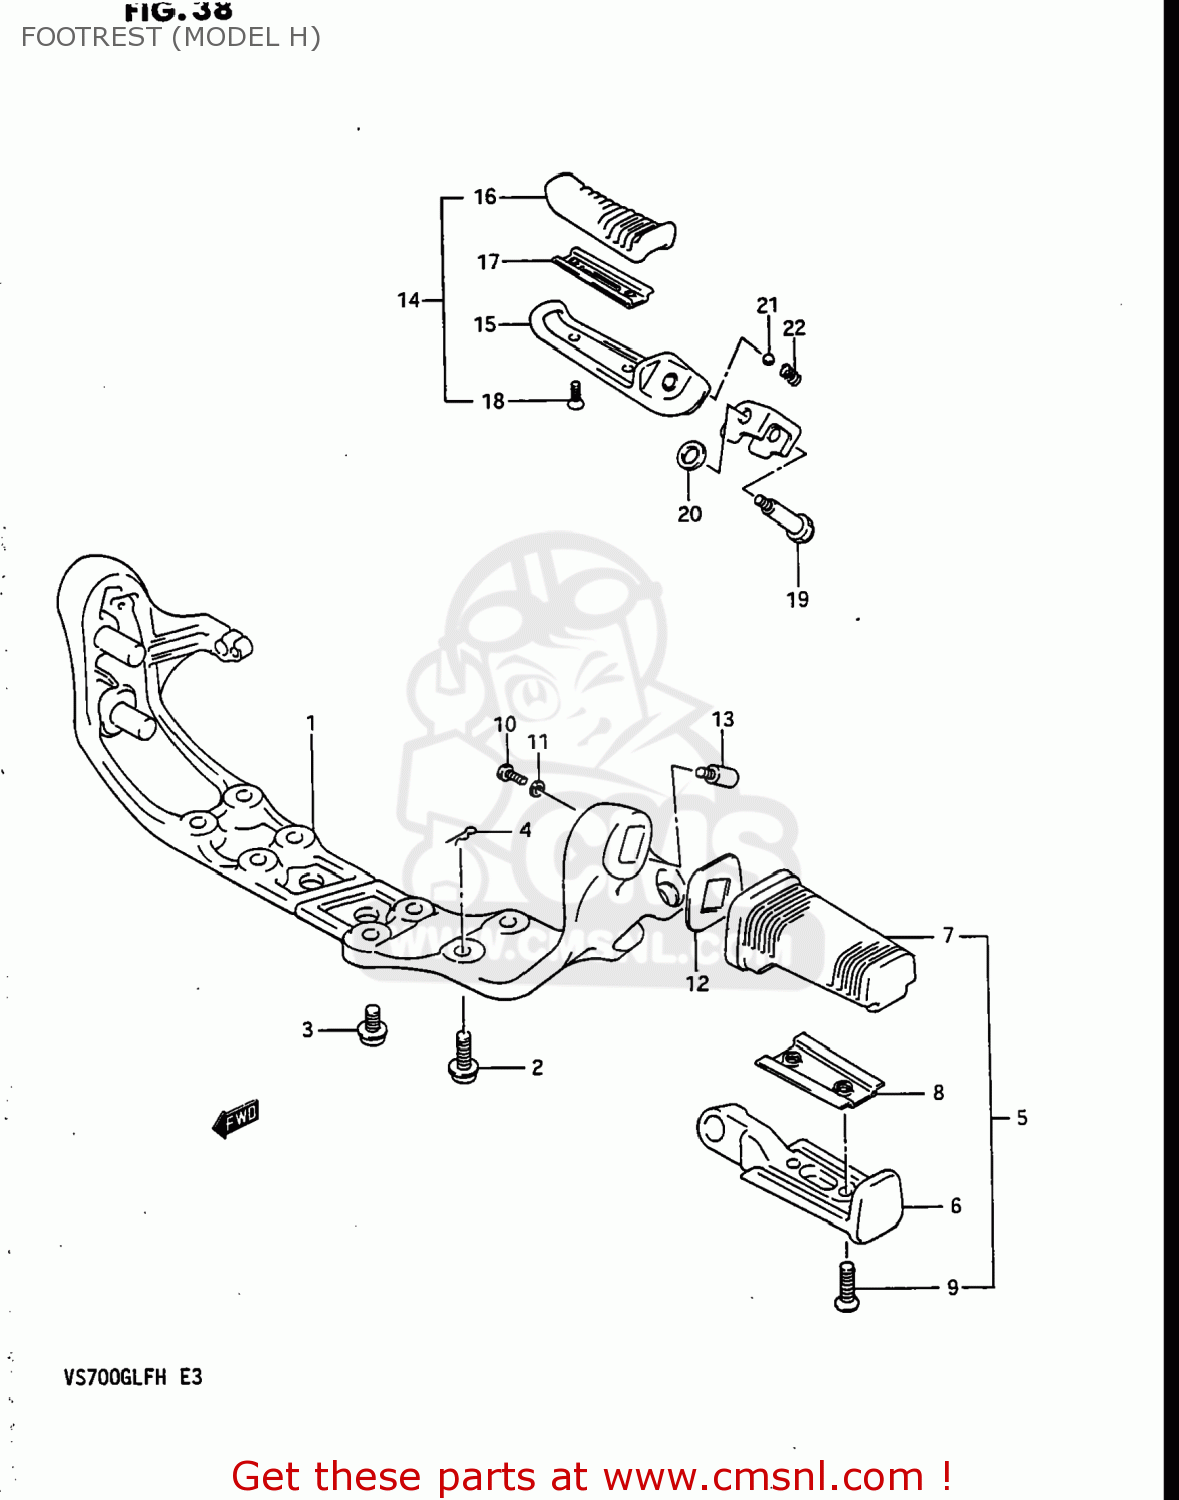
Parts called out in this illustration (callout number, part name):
1	BRACKET COMP,FRONT FOOTREST
2	BOLT(8X25)
3	BOLT
4	PIN,SNAP
5	FOOTREST ASSY,FR,L
6	HOLDER COMP,FRONT FOOT
7	RUBBER,FR FOOTREST
8	PLATE
9	SCREW
10	BOLT 5X12
11	LOCK WASHER
12	WASHER,FRONT FOOTREST
13	BOLT,FRONT FOOTREST
14	FOOTREST ASSEMBLY,REAR
15	BAR COMP,PILLION FOOTREST
16	RUBBER,PILLION FOOTREST
17	PLATE,RUBBER STOPPER
18	SCREW 5X16
19	BOLT(6X34.5)
20	SHIM
21	BALL
22	SPRING
